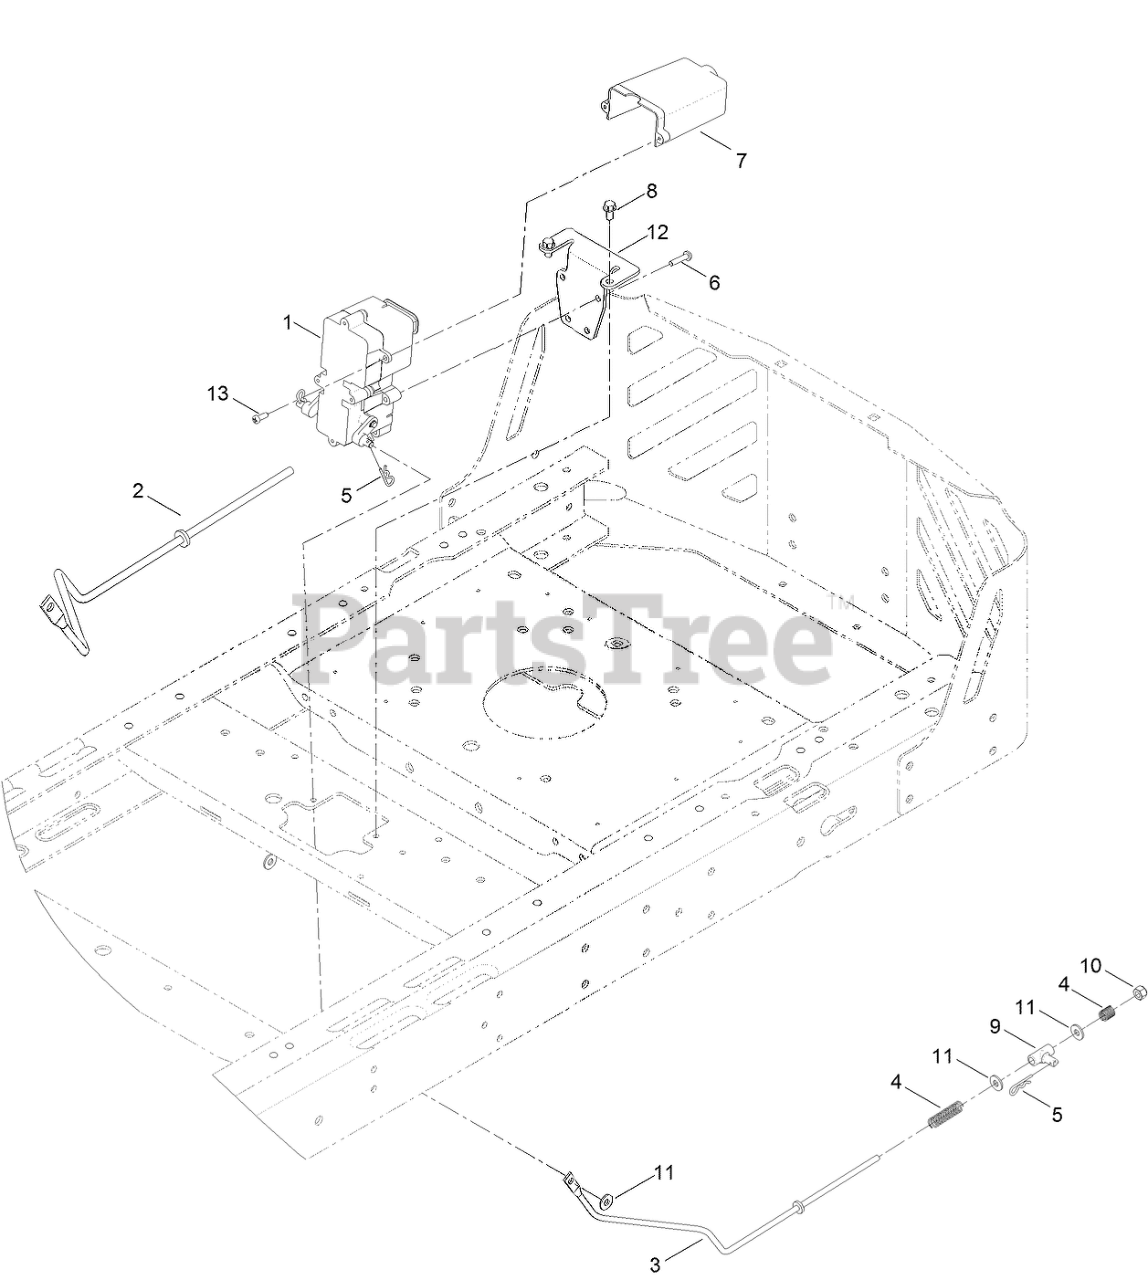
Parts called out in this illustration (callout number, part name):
2	ROD-BRAKE, RH
3	ROD-BRAKE, LH
4	SPRING-COMPRESSION
6	SCREW-PPH
8	SCREW-HWH
9	MOUNT-PIVOT
10	NUT-LOCK, NI
11	WASHER
12	BRACKET-MOUNT, BRAKE
13	SCREW-PPH
